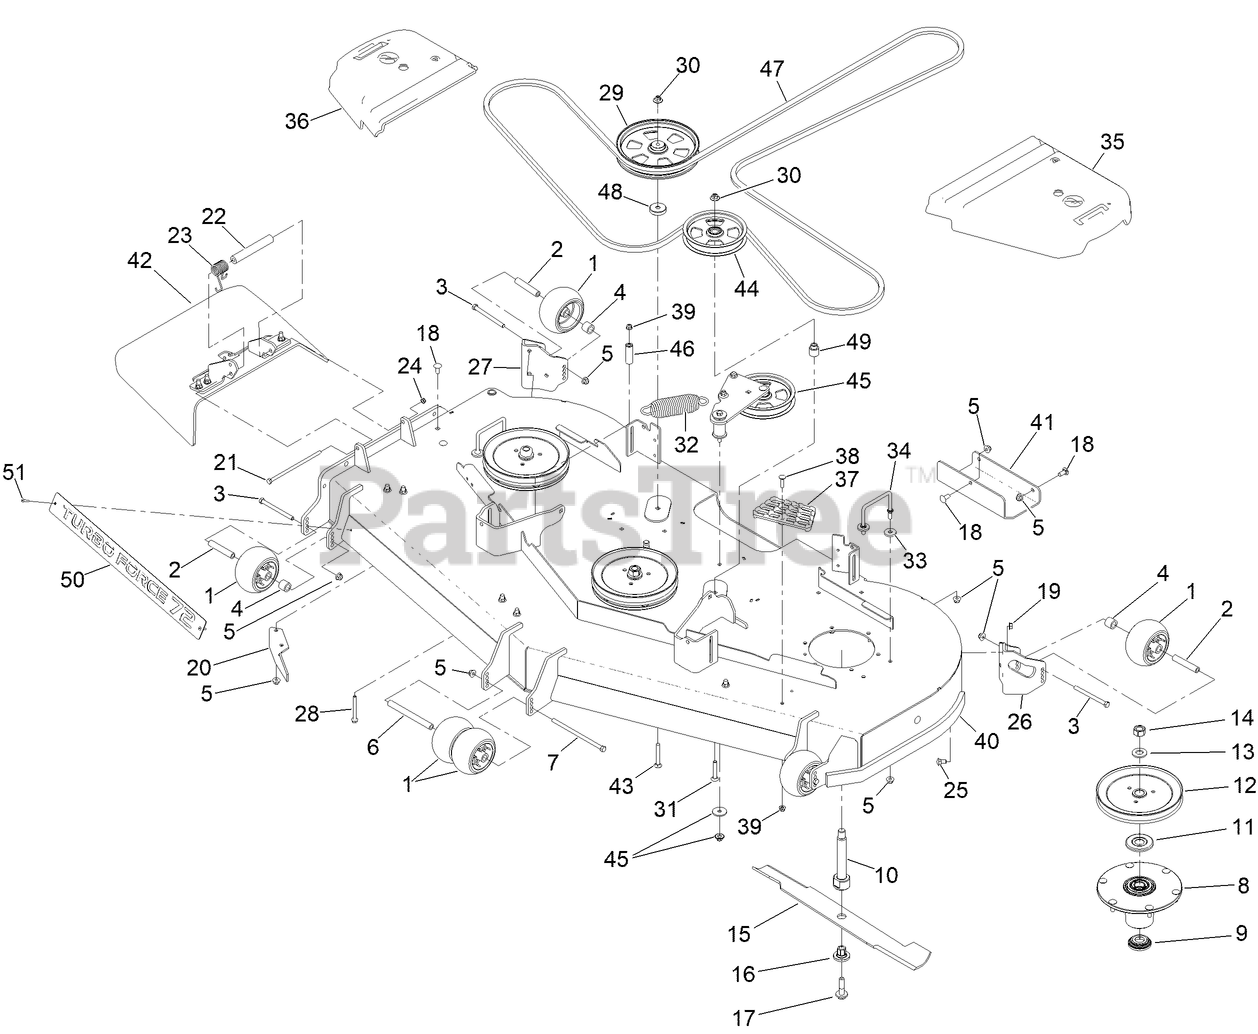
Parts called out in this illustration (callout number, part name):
1	ROLLER-SCALP, ANTI
2	TUBE-SPANNER
3	SCREW-HH
4	TUBE-SPACER
5	NUT-HF, NI
6	SPACER-WHEEL
7	SCREW-HH
8	SPINDLE ASM
9	GUARD-BOTTOM
10	SHAFT-SPINDLE
11	GUARD-BEARING, TOP
12	SHEAVE-DRIVE, BLADE
13	WASHER
14	NUT-HEX
16	BUSHING-HEX
17	SCREW-SEMS
18	SCREW-CARR
19	NUT-HHF, WHIZ
20	BAFFLE-DISCHARGE
21	SCREW-HH
22	SPACER
23	SPRING-TORSION
24	NUT-LOCK, NI
25	SCREW-CARR
26	MOUNT-WHEEL, LH
27	MOUNT-WHEEL, RH
28	SCREW-HHF
29	PULLEY-IDLER,FLAT
30	NUT-FLANGE, NI
31	SCREW-CARR
32	SPRING-EXTENSION
33	WASHER
34	WIREFORM-COVER
35	COVER-BELT, LH
36	COVER-BELT, RH
37	STEP-DECK
38	SCREW-CARR
39	NUT-HF, NI
40	DECK DECAL ASM
41	PLATE-SKID
42	RUBBER DEFLECTOR ASM
43	SCREW-CARR
44	PULLEY-IDLER, FLAT
45	IDLER ARM ASM
46	SPACER-HYDRO
47	BELT, V-5V X 206.6"
48	SPACER-PULLEY
49	BUSHING, IDLER
50	PLATE-TURBO FORCE [BLACK]
51	RIVET-TRIFOLD
